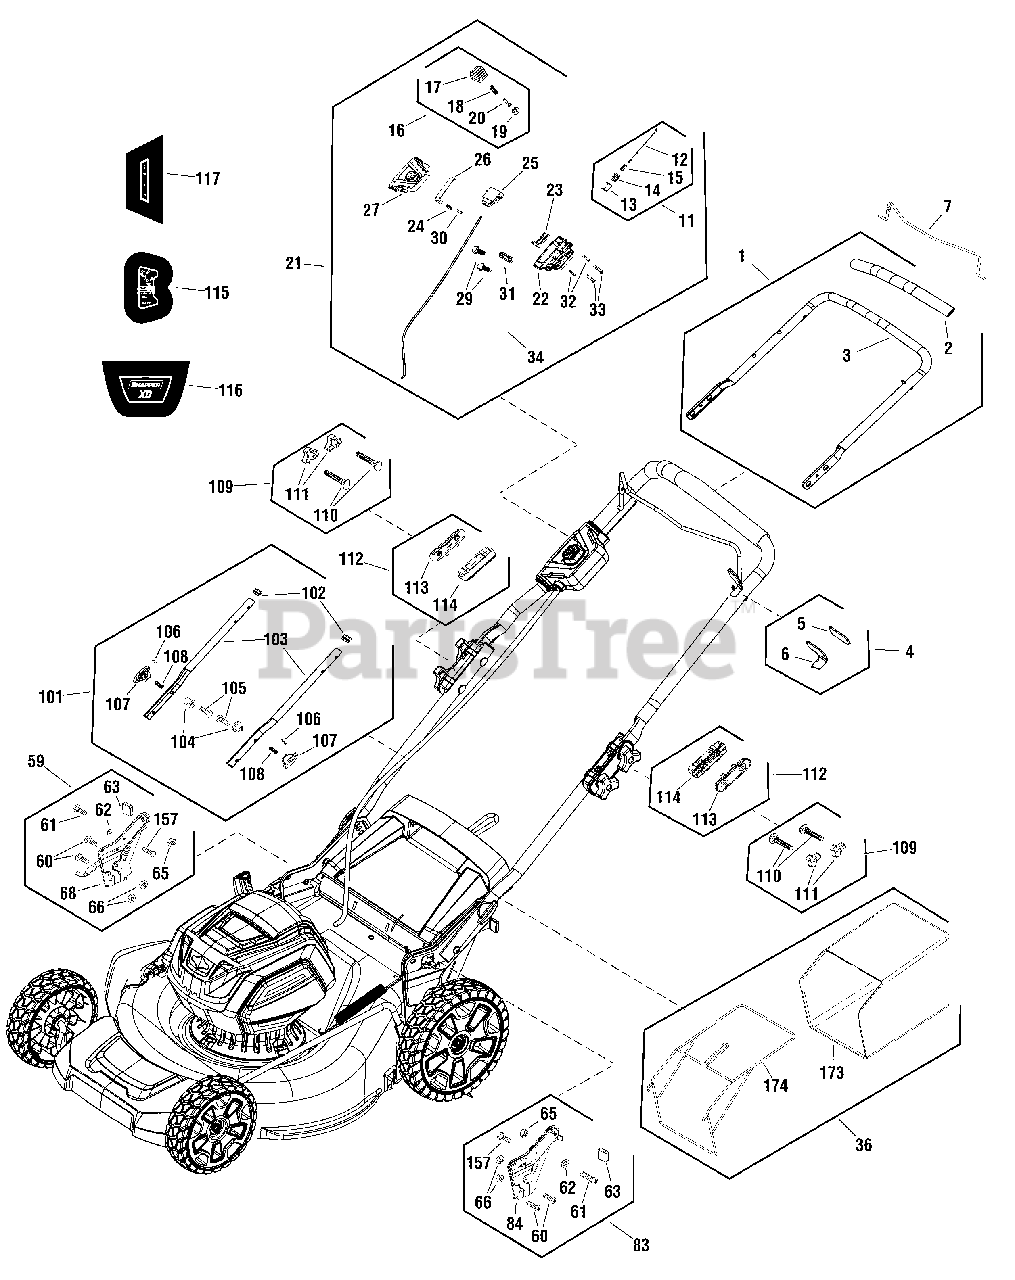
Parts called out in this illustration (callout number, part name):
1	KIT, Upper Handle, NA
2	GRIP, Foam
3	HANDLE, Upper
4	KIT, Stop, Bail
5	SPONGE
6	BRACKET
7	KIT, Bail
11	KIT, Cable
12	CABLE, Bail
13	BRACKET
14	BLOCK
15	SPRING
16	KIT, Button, Start
17	KIT, Speed Control
18	SPRING
19	GASKET
20	SCREW
21	KIT, Control Panel
22	COVER, Bottom
23	BRACKET
24	SPRING
26	PLATE
27	COVER, Top
29	SCREW
30	PIN
31	CLAMP
32	SCREW
33	SCREW
34	WIRE, Yellow
36	GRASS CATCHER ASSEMBLY
59	KIT, Height Adjust, Right, NA
60	BOLT
61	BOLT
62	GASKET
63	BUMPER
65	NUT
66	NUT
68	BRACKET, Height Adjust
83	KIT, Height Adjust, Left
84	BRACKET, Height Adjust
101	KIT, Lower Handle
102	CAP
103	HANDLE, Lower
104	BUSHING
105	SCREW
106	PIN
107	KNOB
108	SPRING
109	KIT, Hardware
110	BOLT
111	KNOB
112	KIT, Handle Bracket
113	BRACKET
114	BRACKET
115	DECAL, Start
116	DECAL, XD Shroud
117	DECAL, Charger
157	SCREW
173	BAG, Grass Catcher
174	FRAME
